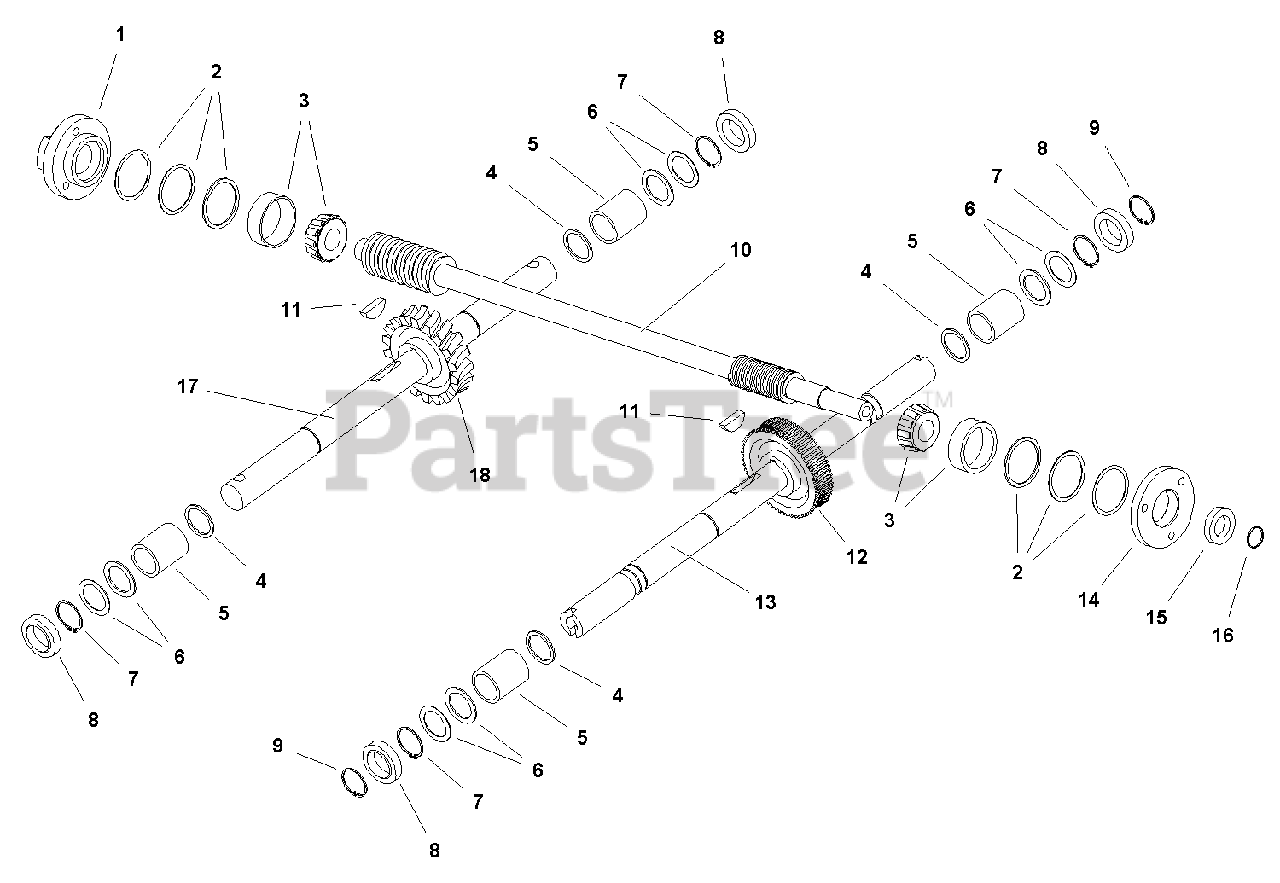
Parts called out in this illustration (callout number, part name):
1	CAP, Rear Bearing
2	SHIM SET, Rear Bearing Cap
2	SHIM, 0.062 THK1-3/4" x OD1806 (As Required)
2	SHIM, 0.030 THK1-3/4" x OD1807 (As Required)
2	SHIM, 0.015 THK1-3/4" x OD1808 (As Required)
2	SHIM, 0.010 THK1-3/4" x OD1809 (As Required)
3	BEARING, Tapered (Cone & Race)
4	SPACER, 1" x 1-1/4"
5	BUSHING
6	SHIM SET, Axle Spacer
6	SHIM, 0.062 THK1-3/8" x OD1705 (As Required)
6	SHIM, 0.030 THK1-3/8" x OD1706 (As Required)
6	SHIM, 0.015 THK1-3/8" x OD1707 (As Required)
6	SHIM, 0.010 THK1-3/8" x OD1708 (As Required)
7	RING, Snap, Internal Retainer
8	SEAL, Housing
9	RING, Snap, External Retainer
10	DRIVE SHAFT, Main
11	KEY, Parallel Plane 1/4" x 1/4" x 1"
12	GEAR, Worm, Wheels Shaft
13	SHAFT ASSEMBLY, Wheel w/Lock Pin 18.25" (6016RT)
13	SHAFT ASSEMBLY, Wheel w/Lock Pin 19.25" (7016RT)
14	CAP, Rear Bearing
15	SEAL, Oil, Drive Shaft
16	WASHER, 5/8
17	SHAFT, Tiller
18	GEAR, Worm Shaft
